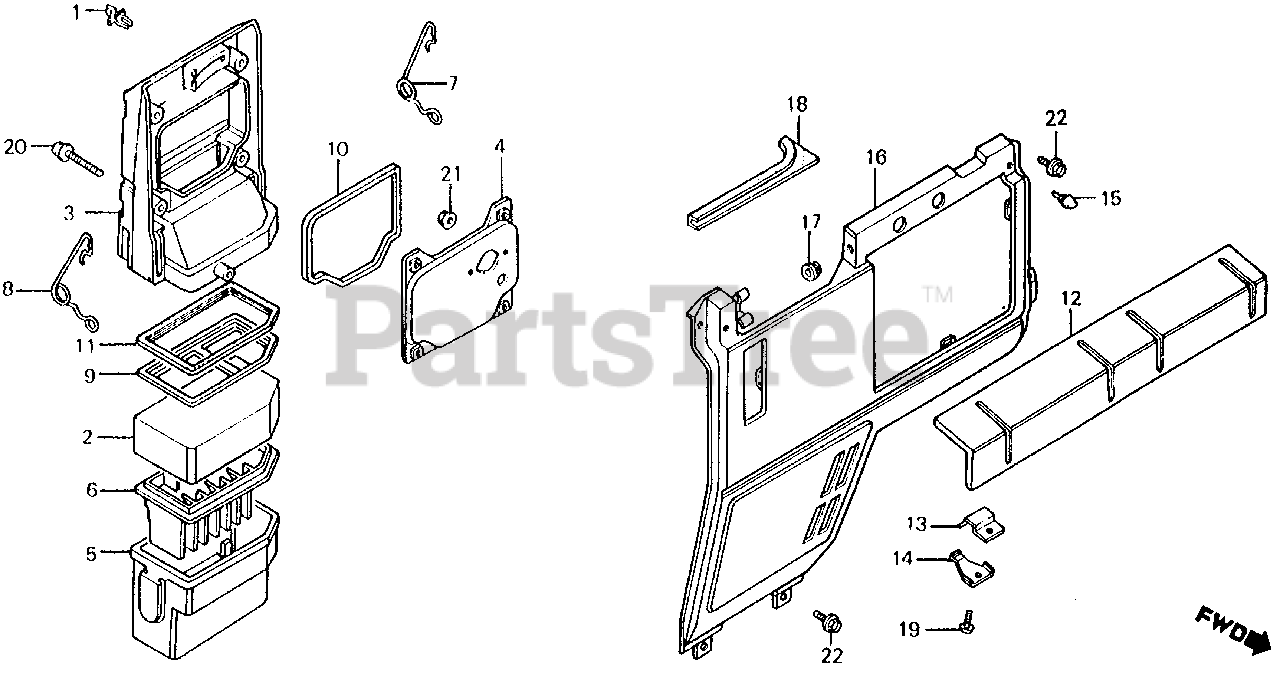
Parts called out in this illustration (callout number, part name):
1	KNOB, MANUAL CHOKE
2	ELEMENT, AIR CLEANER
3	CASE, FR. AIR CLEANER
4	CASE, RR. AIR CLEANER (NOT AVAILABLE)
5	HOUSING, AIR CLEANER (LOWER)
6	BED, AIR CLEANER (LOWER)
7	SPRING, R. AIR CLEANER HOUSING (NOT AVAILABLE)
8	SPRING, L. AIR CLEANER HOUSING (NOT AVAILABLE)
9	HOLDER, ELEMENT
10	RUBBER, AIR CLEANER HOUSING
11	SEAL, AIR CLEANER
12	LID, TOP *NH44MS* (SPECIAL SILVER METALLIC)
12	LID, TOP *NH31* (MCKINLEY WHITE)
12	LID, TOP *R8* (BRIGHT RED)
13	HINGE B, TOP LID
14	SPRING, TOP LID HINGE
15	STOPPER, TOP LID
16	COVER, FR. *R8* (BRIGHT RED)
16	COVER, FR. *NH44MS* (SPECIAL SILVER METALLIC)
16	COVER, FR. *NH31* (MCKINLEY WHITE) (NOT AVAILABLE)
17	GROMMET, TOOL
18	RUBBER, GUARD
19	SCREW, PAN (5X8)
20	SCREW-WASHER (5X28)
21	NUT, FLANGE (5MM)
22	BOLT, FLANGE (6X10)
